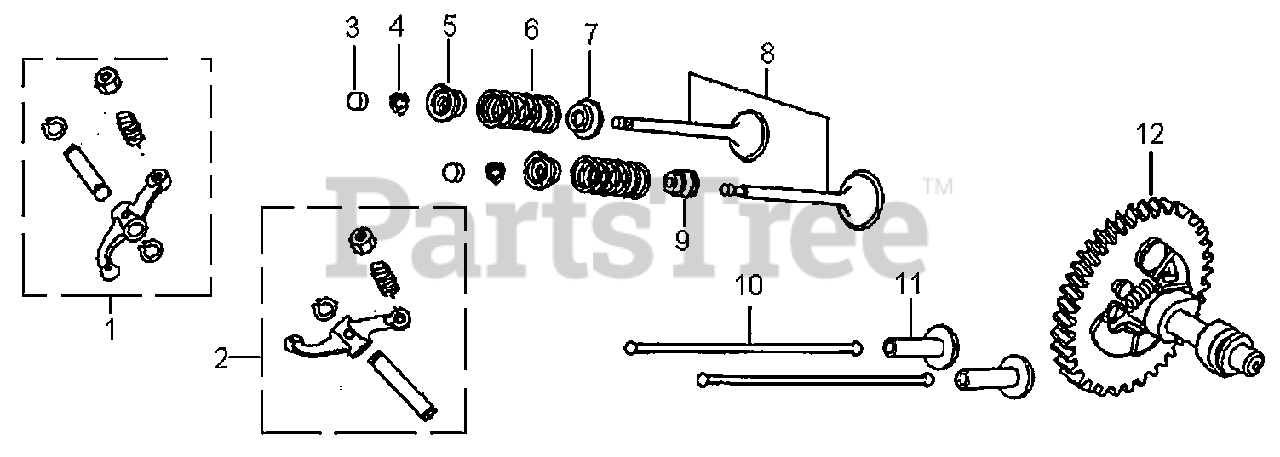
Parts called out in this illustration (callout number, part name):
1	ROCKER ARM ASSY.
2	ROCKER ARM ASSY.
3	ROTATOR,VALVE
4	VALVE LOCKER
5	RETAINER,VALVE SPRING
6	SPRING,VALVE
7	SEAT,VALVE SPRING
8	VALVE ASSY.
9	SEAL,VALVE STEM
11	LIFTER , VALVE
12	CAMSHAFT ASSY
